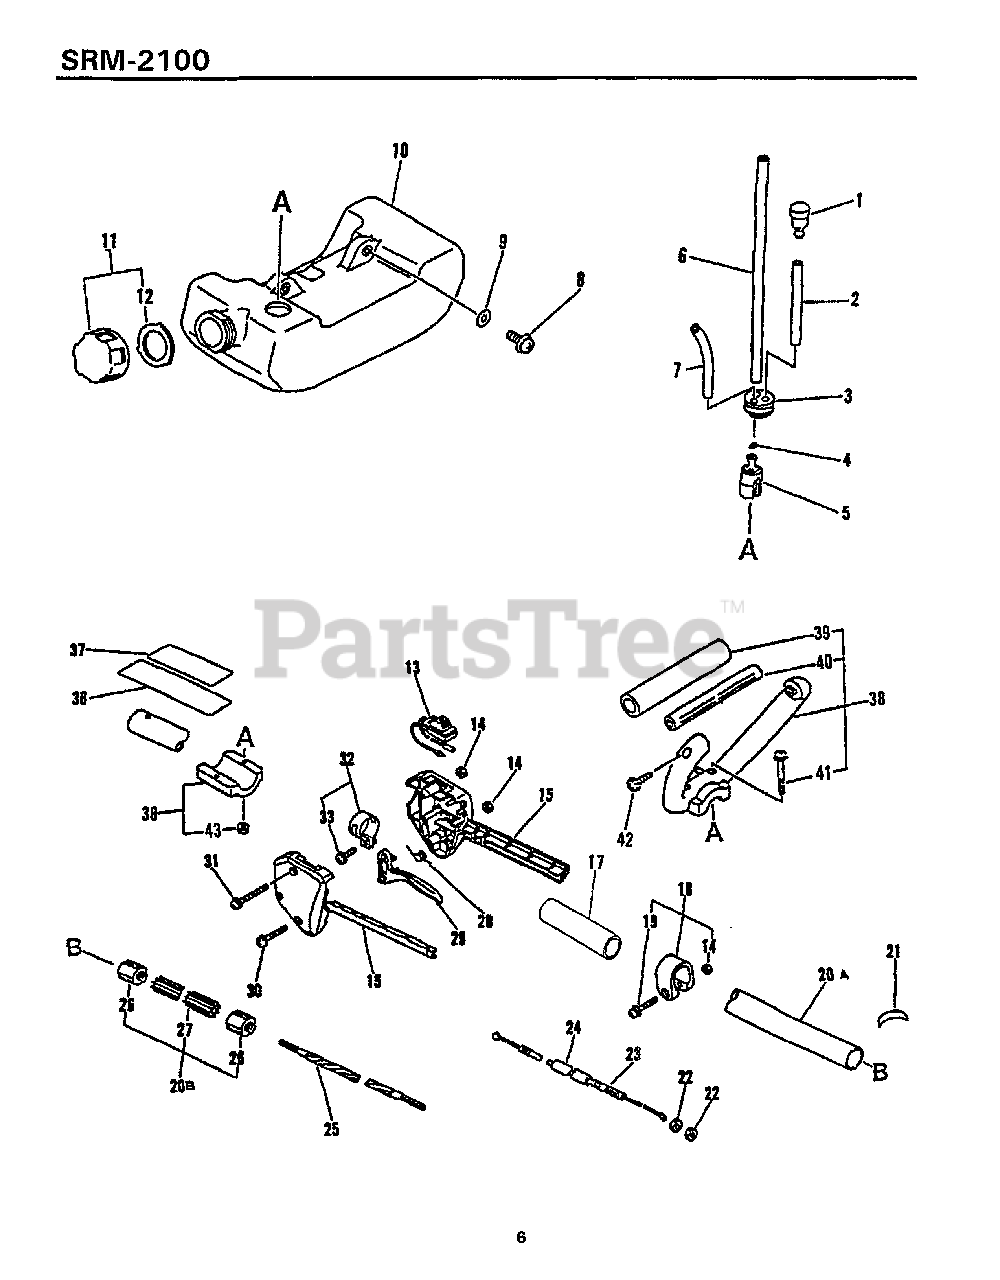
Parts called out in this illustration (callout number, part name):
1	VENT ASSY
2	PIPE K43B3×5×70
3	GROMMET, FUEL Ø5
4	CLIP 6 MM
5	FILTER, FUEL
6	PIPE, FUEL
7	PIPE 3×5×90
8	SCREW 5×16
9	WASHER 5.5×12×0.8
10	TANK, FUEL
11	CAP ASSY
12	GASKET, FUEL CAP
13	IGNITION SWITCH ASSY
14	NUT M5
15	HANDLE KIT, CONTROL
17	GRIP, HANDLE
18	CLAMP KIT
19	SCREW 5×30
20	MAIN PIPE ASSY 25×1500
21	LABEL - ALIGNMENT
23	CABLE, THROTTLE
25	DRIVESHAFT - FLEXIBLE L= 1522
27	LINER - FLEXIBLE
28	SPRING, TORSION
29	TRIGGER, THROTTLE
30	SCREW 5×25
31	SCREW 5×35
32	CLAMP KIT
33	SCREW 5×14
36	LABEL - CAUTION
37	LABEL - CAUTION
38	LOOP HANDLE ASSY
39	GRIP, HANDLE
41	SCREW 6×25
42	SCREW 5×30
43	NUT, HEX M6
